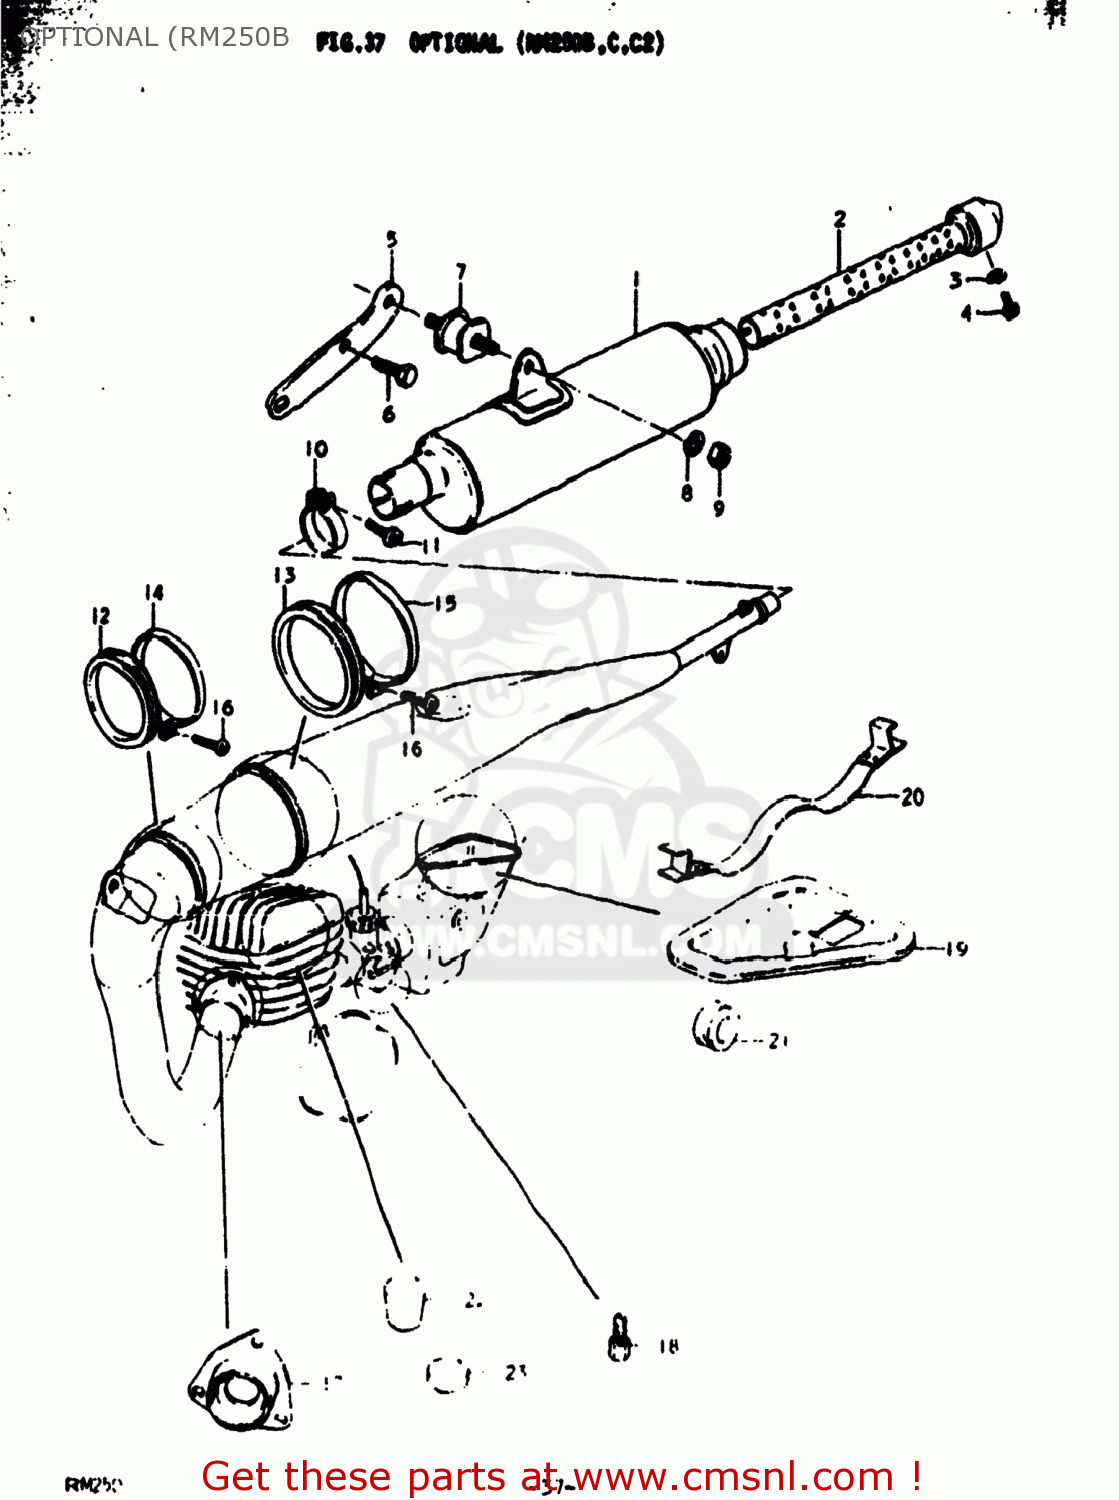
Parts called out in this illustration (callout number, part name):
0	OFF-ROAD SOUND KIT
1	MUFFLER ASSEMBLY
2	PIPE,MUFFLER BAFFLE
3	LOCK WASHER
4	SCREW
5	BRACE,MUFFLER
6	BOLT
7	DAMPER,MUFFLER SUPPORT
8	LOCK WASHER
9	NUT
10	CLAMP
11	SCREW
12	BODY,MUFFLER
13	BODY,MUFFLER
14	CLAMP
15	CLAMP
16	SCREW
17	FLANGE,EXHAUST PIPE
18	JET
19	CAP,AIR CLEANER
20	HOLDER,FILTER
22	PAD,CYLINDER HEAD
23	PAD,CYLINDER HEAD
